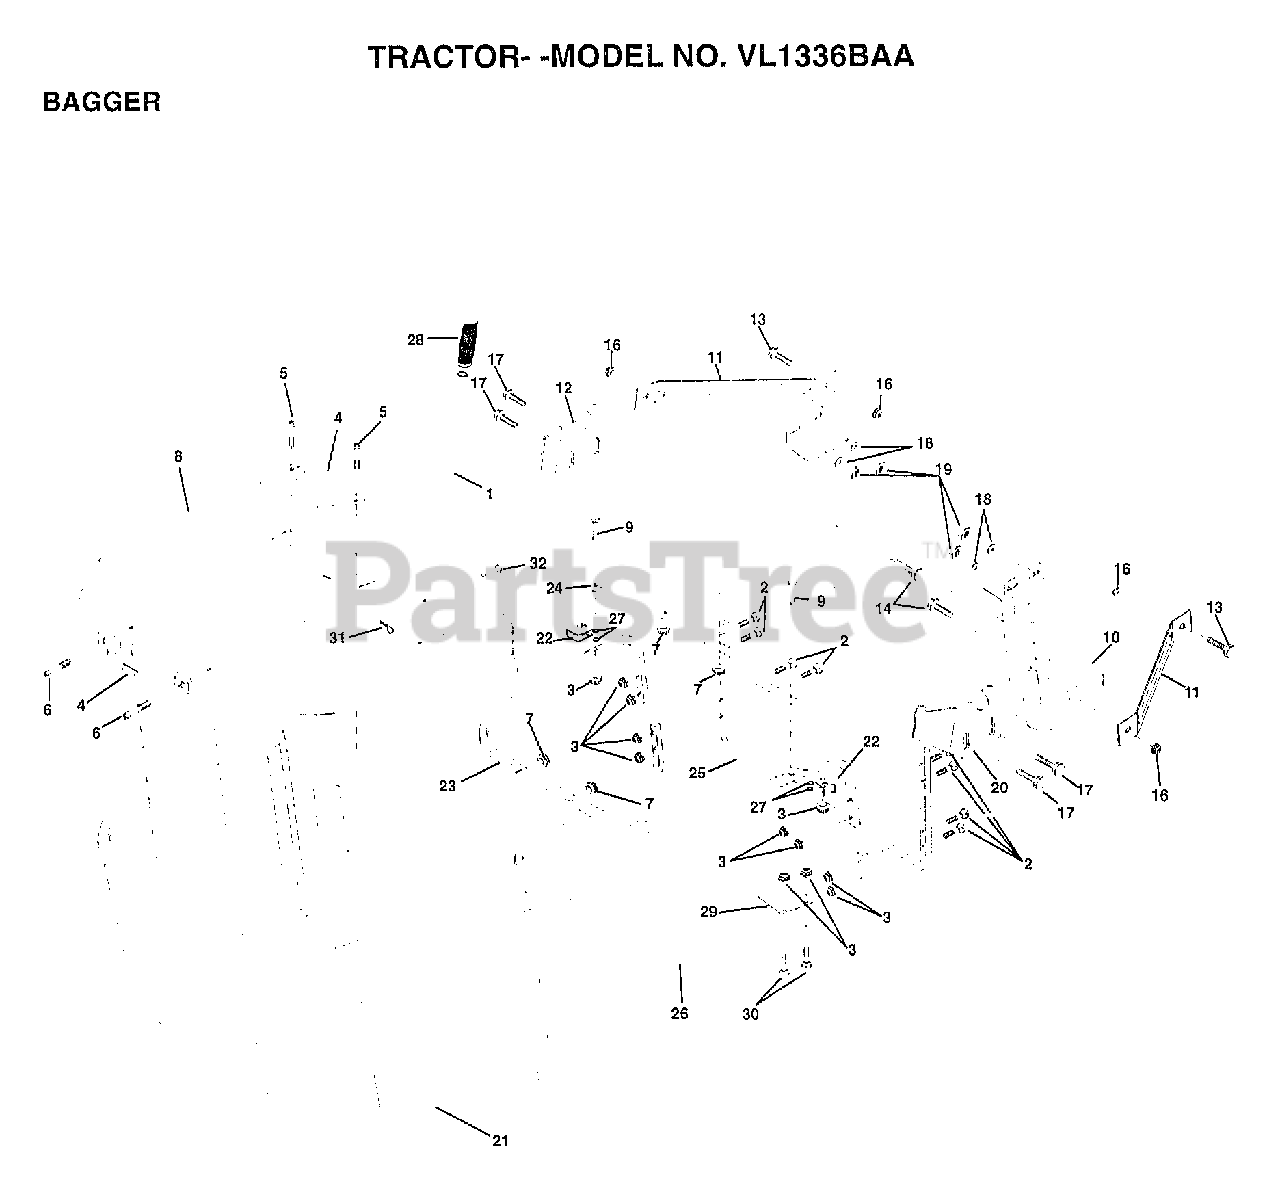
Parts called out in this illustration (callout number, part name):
1	TUBE.HDLE.BAG.CRD
2	BOLT.CARRIAGE.1/4-20X2.0
4	HANDLE.GRAB.BLACK.
5	"SCREW,PAN.HEAD"
8	COVER.BAGGER.CRD
9	BOLT CARRIAGE
10	SUPT.ASM.WLDMNT.BAG.CRD
11	BRKT.SUPT.UPPER.BAG.CRD
12	BRKT.PIVOT.BAG.LH.CRD
13	BOLT
14	BOLT.HEX.3/8-16X2-1/2
17	BOLT
18	WASHER
19	NUT
20	"BRKT.PIVOT.BAG,RH.CRD"
21	BAG.ASM.CRD
22	BRKT.SIDE.BAG.CRD
23	TUBE.UPPER.BAG.CRD
24	TUBE.PIVOT.BAG.CRD
25	TUBE.FT.BAG.CRD
26	TUBE.LOWER.BAG.CRD.
27	GROMMET.EXTRUDED
28	GRIP.HANDLE.BLACK
29	PLATE.STOP.BAG.HDLE.CRD
30	BOLT.CARRIAGE
31	RETAINER M
32	RIVET.DRILL.1.75
